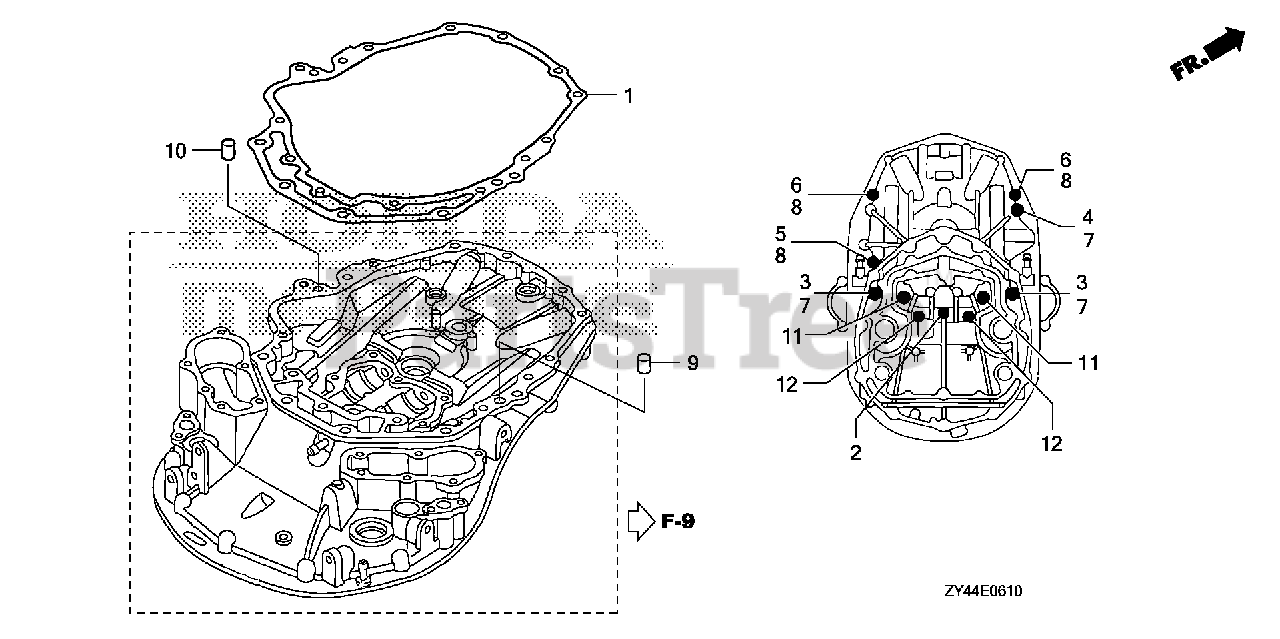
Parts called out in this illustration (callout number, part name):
1	GASKET, MOUNT CASE
2	BOLT, FLANGE (10X120) (SATO)
3	BOLT, HEX. (12X120)
4	BOLT, HEX. (12X65)
5	BOLT, HEX. (10X85)
6	BOLT, HEX. (10X60)
7	WASHER, PLAIN (12MM)
8	WASHER, PLAIN (10MM)
9	PIN, DOWEL (14X15)
10	PIN B, DOWEL (10X16)
11	BOLT, FLANGE (10X70)
12	BOLT, FLANGE (12X120)
